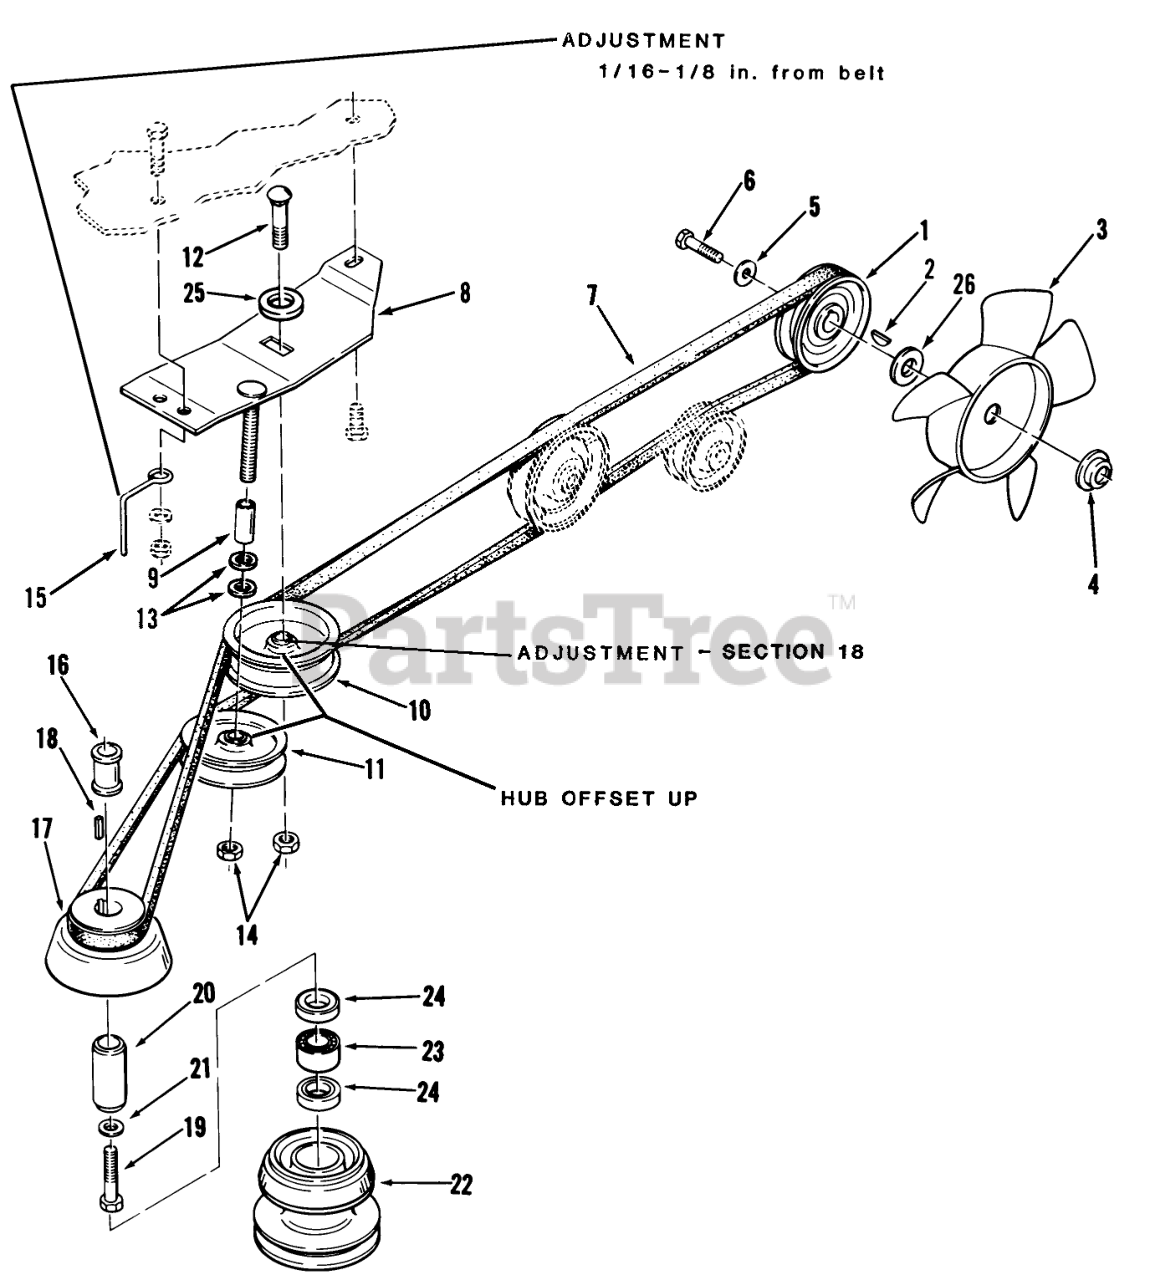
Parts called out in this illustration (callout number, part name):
1	PULLEY
2	KEY WOODR 1/8X1/2 DI
3	BLADE - FAN
4	SPACER FAN
5	WASHER
6	Bolt
7	BELT V
8	ASSY PULLEY BRACK R
9	Spacer
10	Flat Idler
11	PULLEY-IDLER STATION
12	Bolt
13	Washer
14	Nut
15	Belt Retainer
16	TUBE SPACER
17	PULLEY-ENGINE
19	HEX HD CAP SCREW
20	RACE BEARING
21	WASHER
22	Assy Pulley Mwr Dr
23	BRG-NEEDLE OPEN END
24	SEAL-OIL
25	Washer
26	Special Washer
